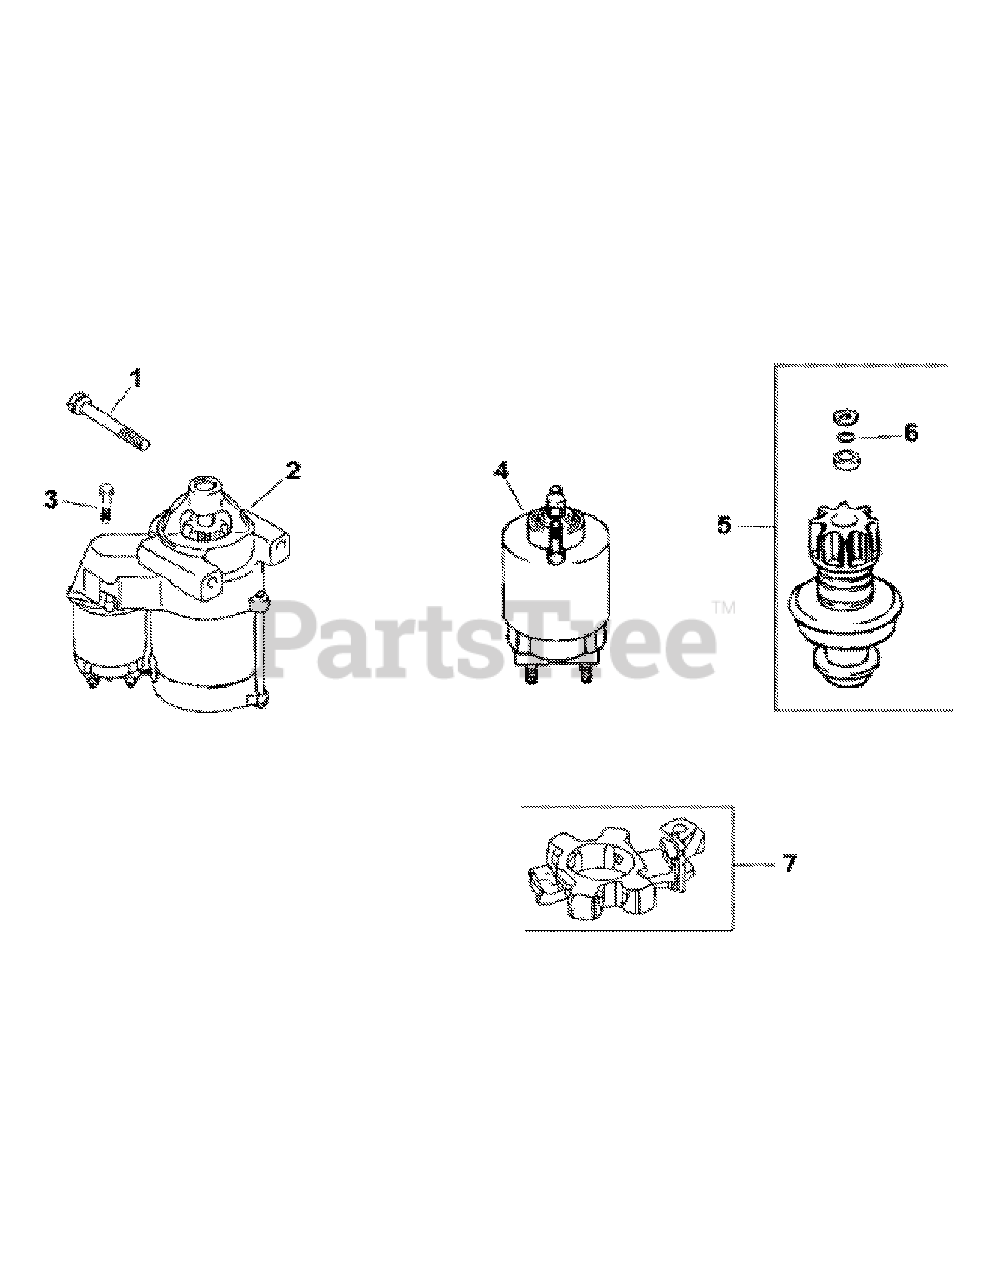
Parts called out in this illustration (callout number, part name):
1	Hex Flange Screw
2	Solenoid Shift Starter
3	Torx Head Screw
4	Solenoid Kit
5	Starter Pinion Kit
